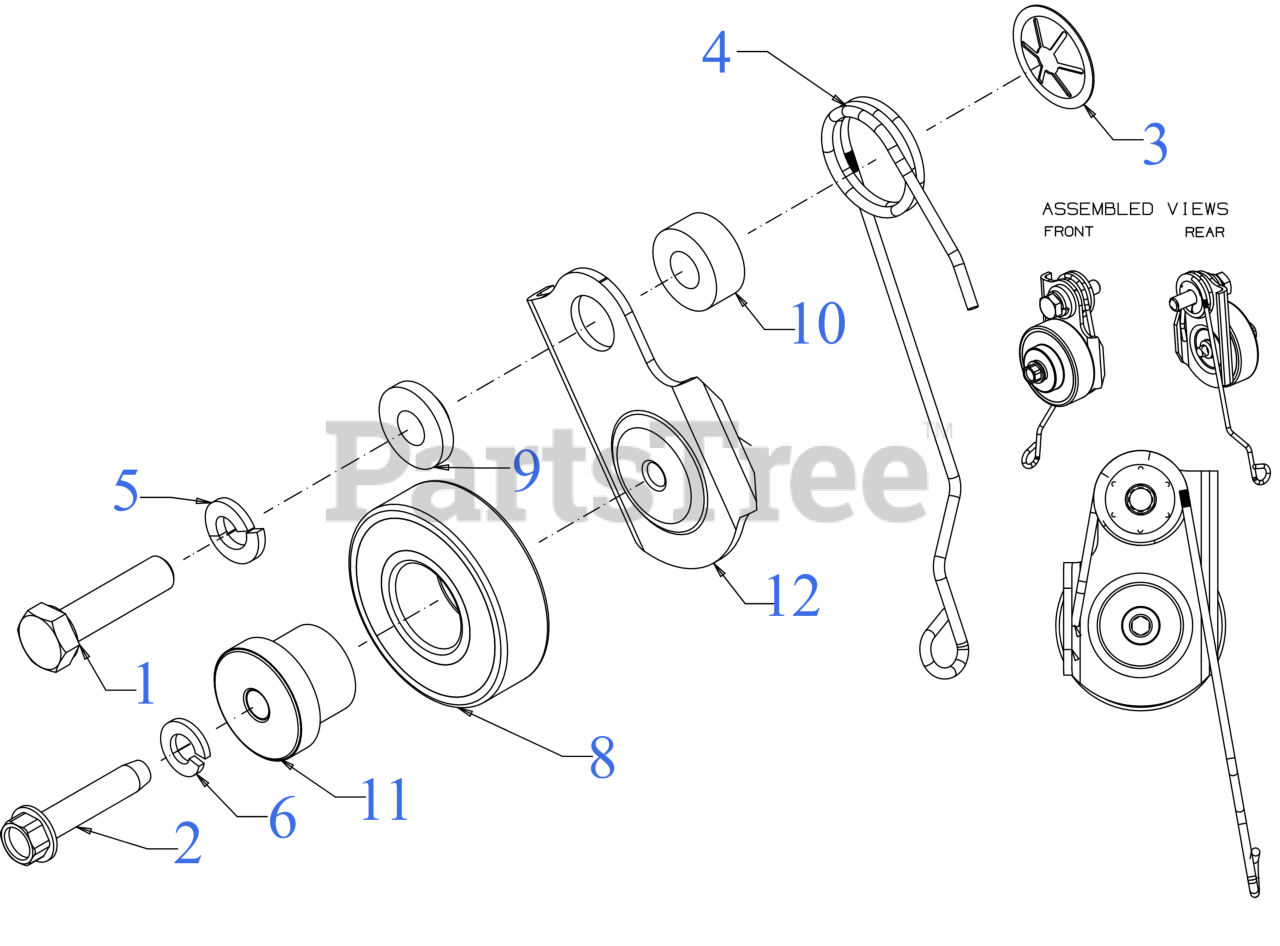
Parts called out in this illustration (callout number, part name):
1	SCREW 5/16-24 x 1.25 GR5
2	SCREW 1/4-20 x 1.25
3	PUSH ON NUT
4	TORSION SPRING
5	LOCK WASHER 5/16
6	LOCK WASHER
8	BALL BEARING
9	SHOULDER SPACER
10	IDLER BRACKET SPACER .340X.750X.330
11	SHOULDER SPACER
12	IDLER BRACKET
